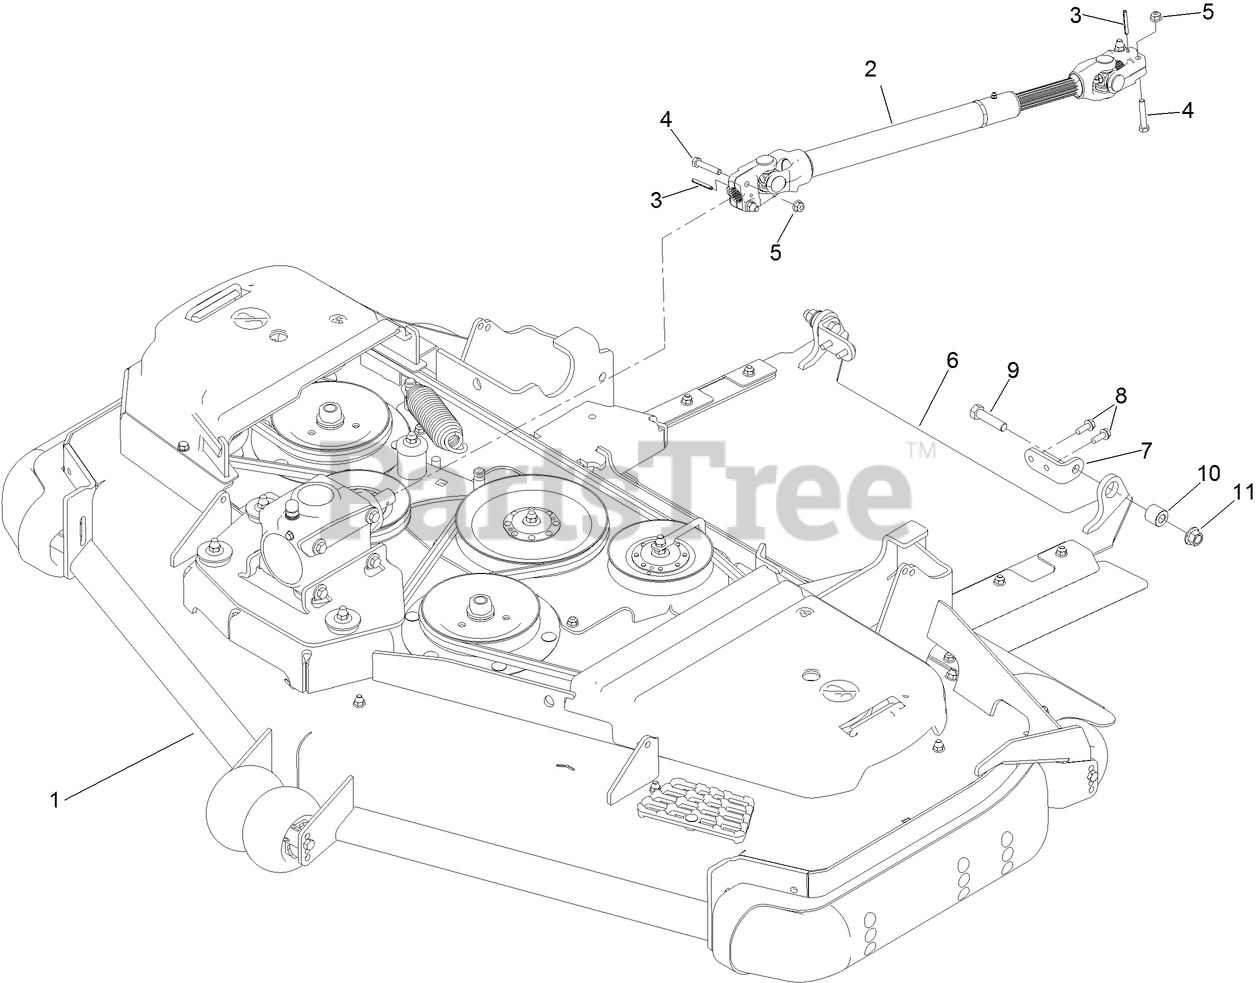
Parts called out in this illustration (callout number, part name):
2	DRIVESHAFT ASM
3	PIN-ROLL
4	SCREW-HH
5	NUT-HF, NI
6	DISCHARGE TUNNEL ASM
7	BRACKET-DISCHARGE
8	SCREW-TAPTITE
9	SCREW-HH
10	BUSHING-SLEEVE
11	NUT-LOCK
